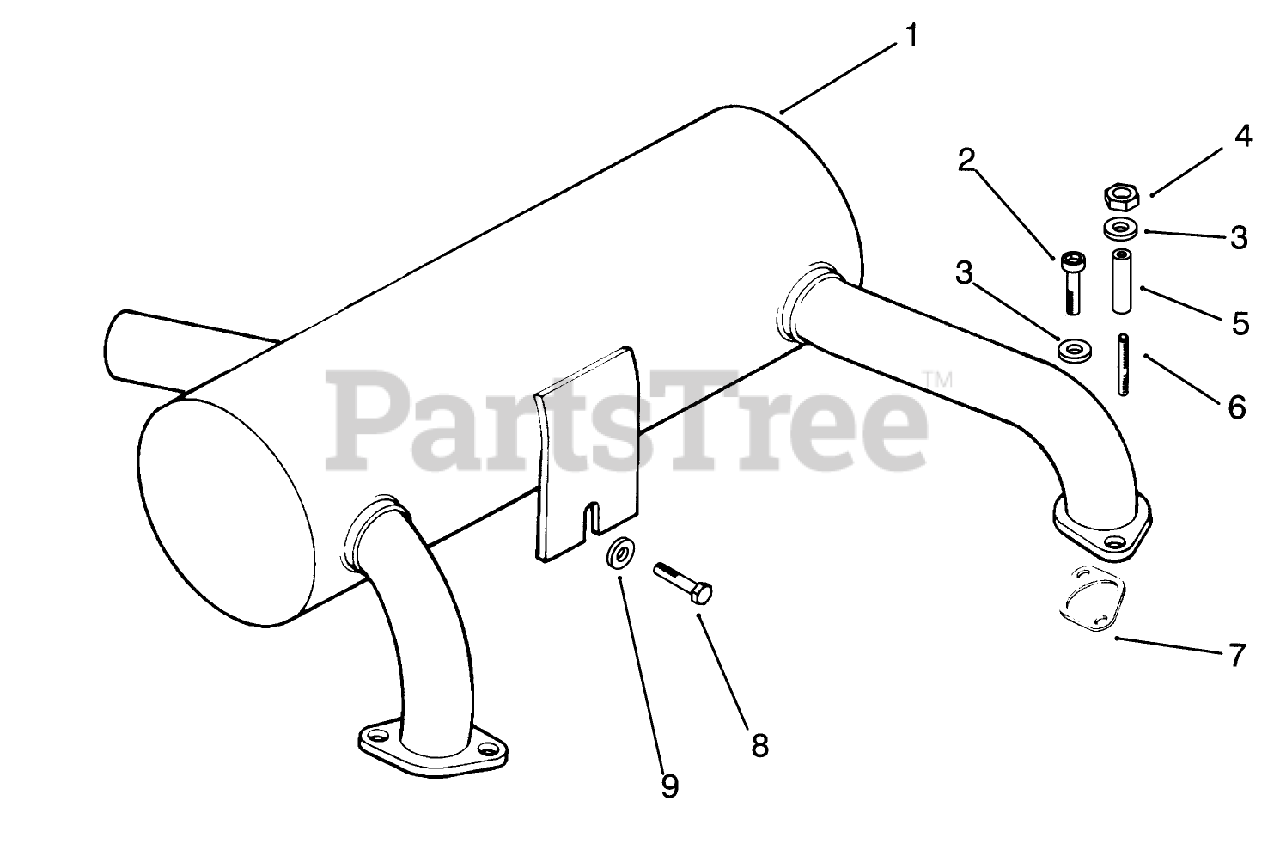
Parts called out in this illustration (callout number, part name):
1	Muffler
2	Screw
3	Washer-Lock
4	Nut
7	Gasket Exhaust
8	Screw
9	Washer
